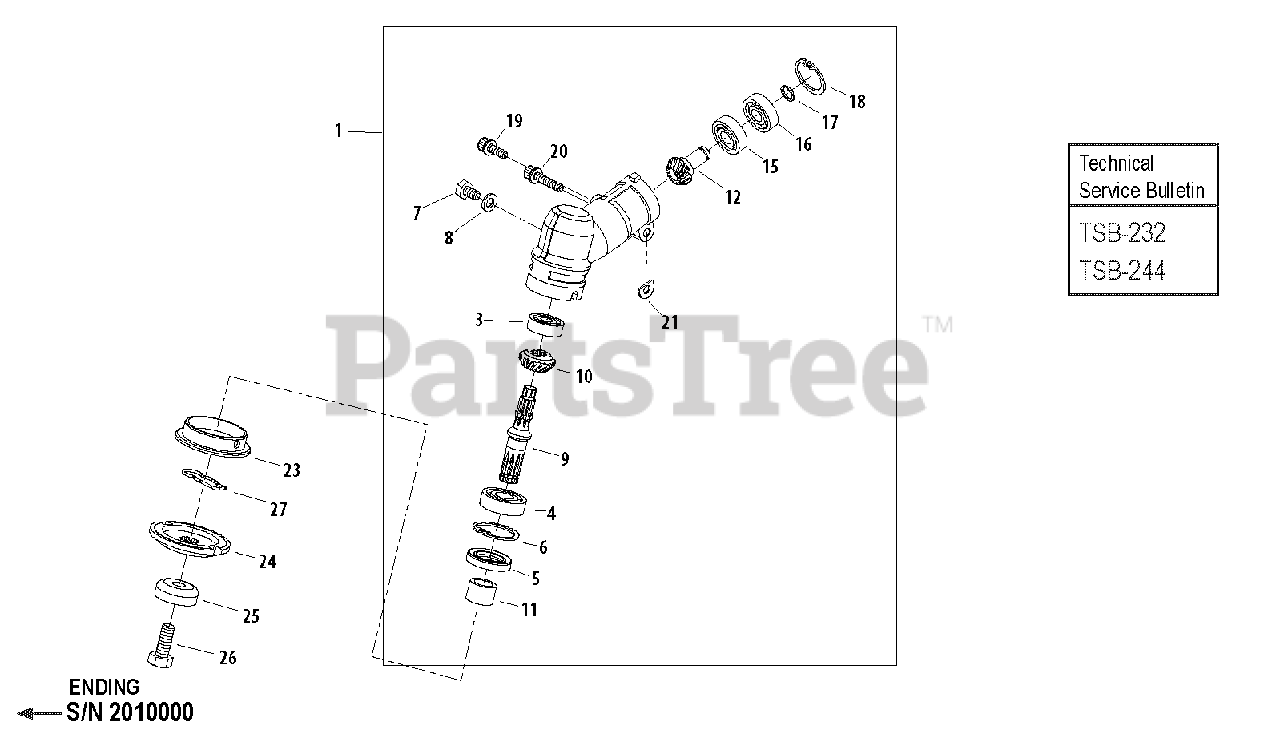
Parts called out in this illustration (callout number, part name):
1	GEAR CASE ASSY
3	BEARING, BALL 608 DDU
4	BEARING, BALL 6001
5	SEAL, OIL
6	RING, SNAP Ø28
7	BOLT M6×10
8	WASHER 6.5×11.5×0.8
9	SHAFT, GEAR
10	GEAR SET
11	SPACER
12	GEAR SET
15	BEARING, BALL 609
16	BEARING, BALL 609ZZ
17	RING, SNAP
18	RING, SNAP Ø24
19	BOLT M5×16
20	BOLT M5×25
21	D-WASHER
23	PLATE, ADAPTOR - UPPER
24	PLATE, ADAPTOR - LOWER
25	GUARD, BOLT
26	BOLT 8
27	CLIP, BLADE
